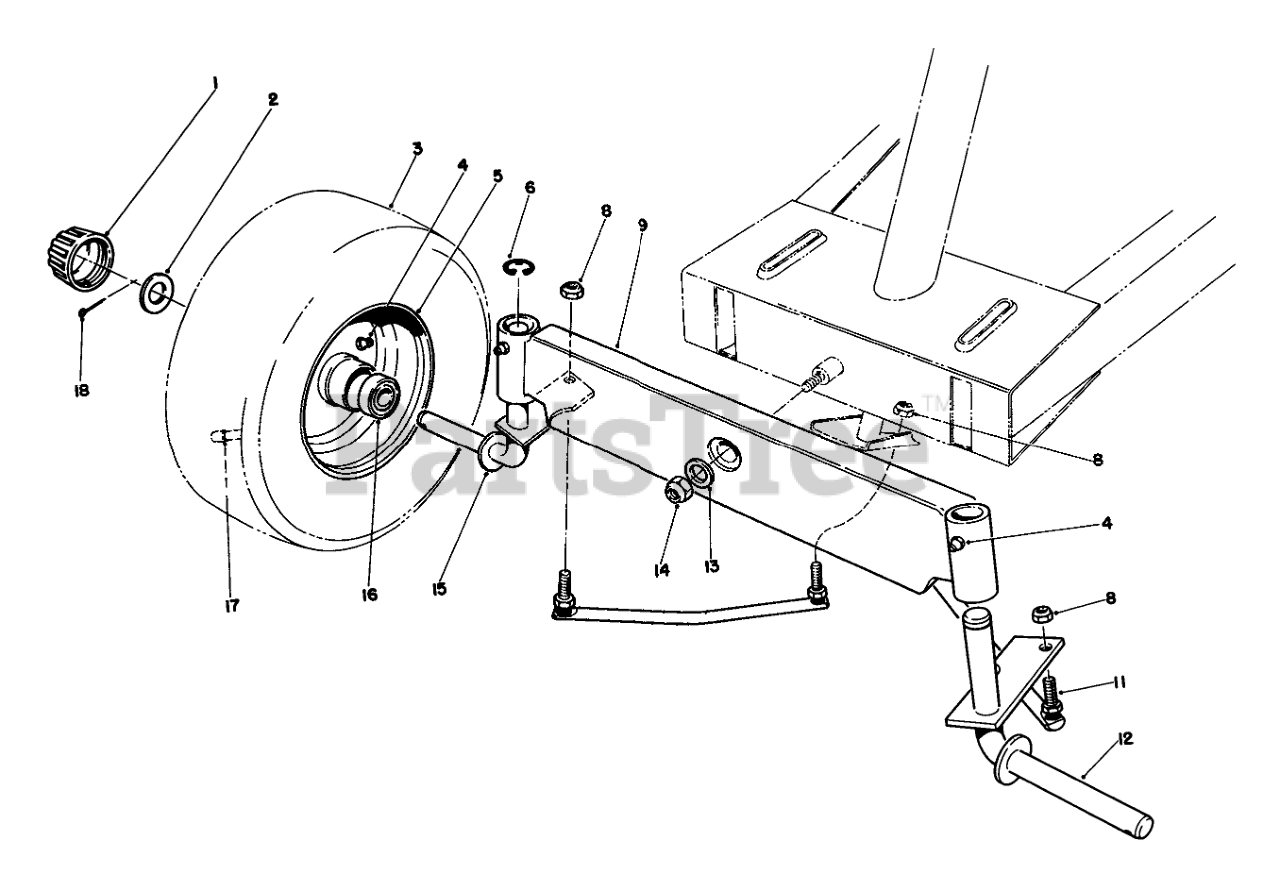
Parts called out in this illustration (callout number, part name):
1	CAP-HUB
2	WASHER-PLAIN
3	TIRE,PNEU.11X4.00X5
4	FITTING-GREASE
6	E-RING
8	NUT-LOCK
9	Axle-Front
11	TIE ROD ASM
12	Spindle-L.H.
13	WASHER-FLAT
14	NUT-LOCK, NI
15	Spindle-R.H.
16	Bearing
17	STEM-VALVE
18	PIN-COTTER
